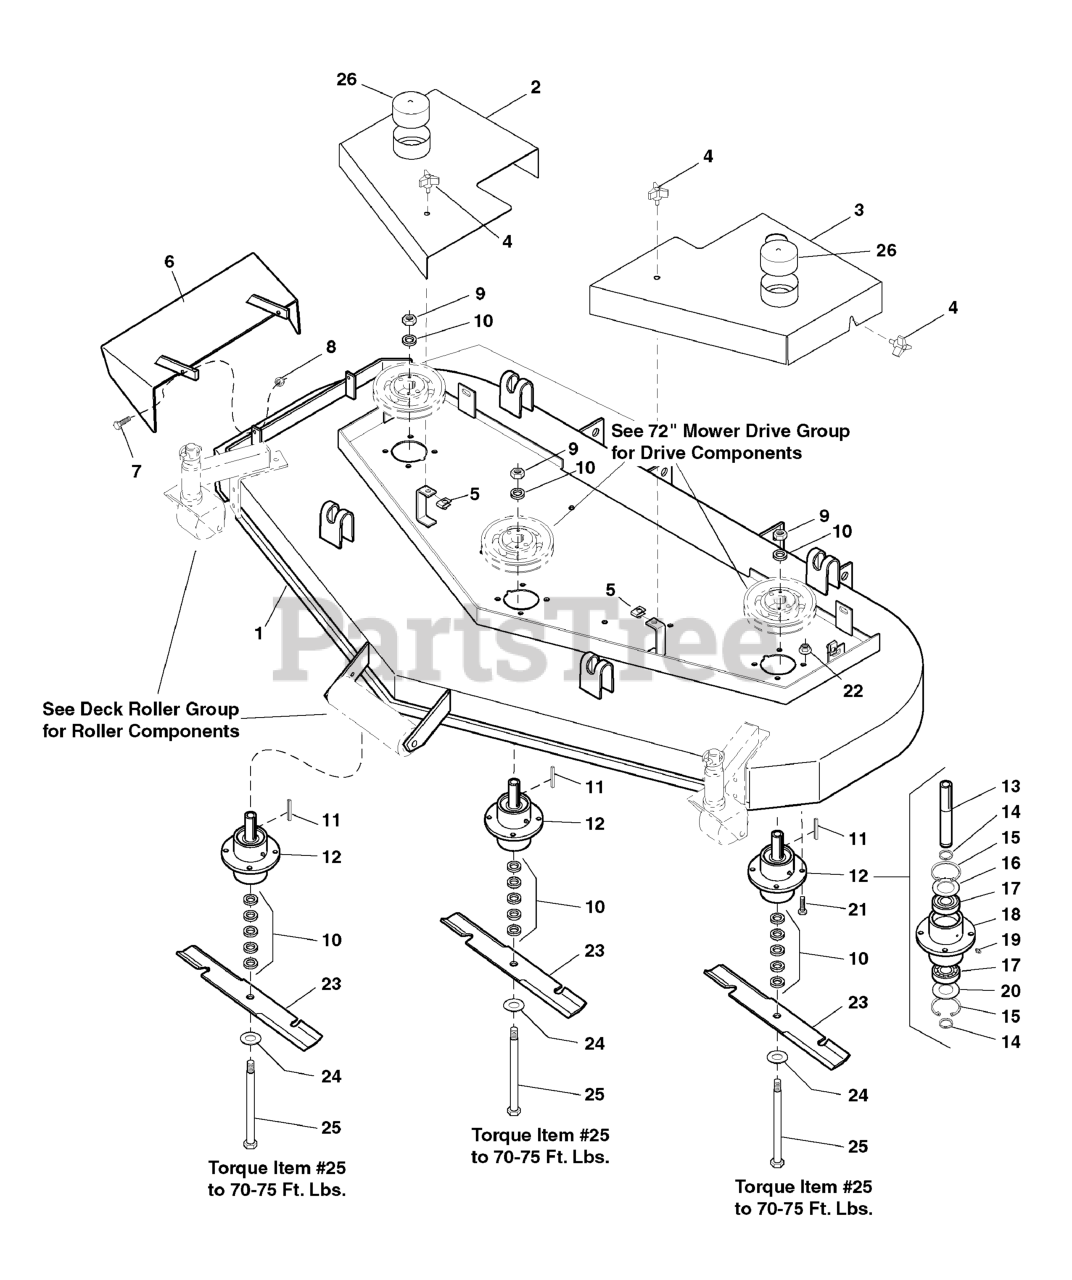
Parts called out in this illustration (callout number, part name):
1	DECK SHELL W/DECALS, 72"
2	SPINDLE COVER-RH
3	SPINDLE COVER-LH
4	KNOB
5	BODY CLIP, 5/16-18-7GA MATERIAL
6	DISCHARGE CHUTE
7	BOLT, 5/16-18 X 1 GD5 YZ
8	NUT, 5/16-18 Hex Nylon Lock
9	NUT, 5/8-11 Hex
10	SPACER, .63 x 1.06 x .23
11	KEY, 1/4 SQ. X 2-1/2
12	SPINDLE ASSEMBLY, Complete
13	SPINDLE SHAFT
14	SNAP RING, External
15	SNAP RING, Internal
16	SPINDLE WASHER, Top
17	BEARING
18	SPINDLE HOUSING
19	GREASE FITTING
20	SPINDLE WASHER, Bottom
21	BOLT, 5/16-18 x 1-1/4
22	NUT, 5/16-18 HEX SERRATED FLANGE (LARGE)
23	BLADE, 25" (SET OF THREE)
24	WASHER, 5/8" USS
25	BOLT, 5/8-11 x 9-1/2
26	VINYL CAP
